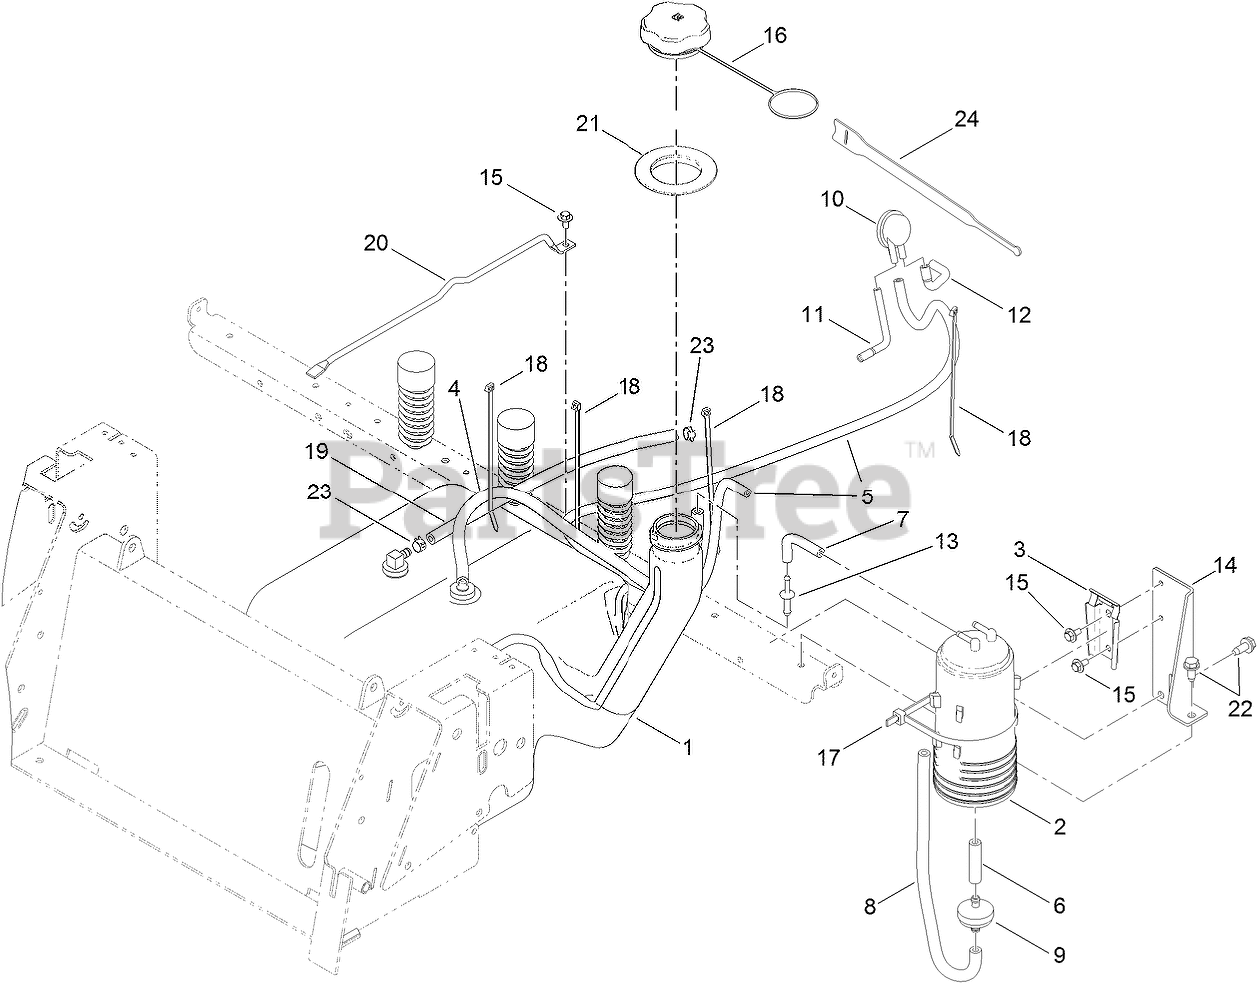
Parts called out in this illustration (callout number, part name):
1	FUEL TANK ASM
2	CANISTER-CARBON, 800CC
3	BRACKET-CANISTER, CARBON
4	HOSE-FUEL
5	HOSE-FUEL
6	HOSE-FUEL
7	HOSE-FUEL
8	HOSE-FUEL
9	FILTER-FUEL, INLINE
10	VALVE-CONTROL, VACUUM
11	HOSE-VENT, FORMED
12	HOSE-VENT, FORMED
13	ADAPTER-ORIFICE
14	BRACKET-MOUNTING, CANISTER
15	SCREW-HHFTF
16	CAP-FUEL
17	TIE-CABLE
18	TIE-CABLE
19	HOSE-FUEL
20	ROD-TANK, GAS
21	SEAL-TANK
22	SCREW-HWHTF
23	CLAMP-HOSE
24	STRAP-VELCRO, CABLE TIE
